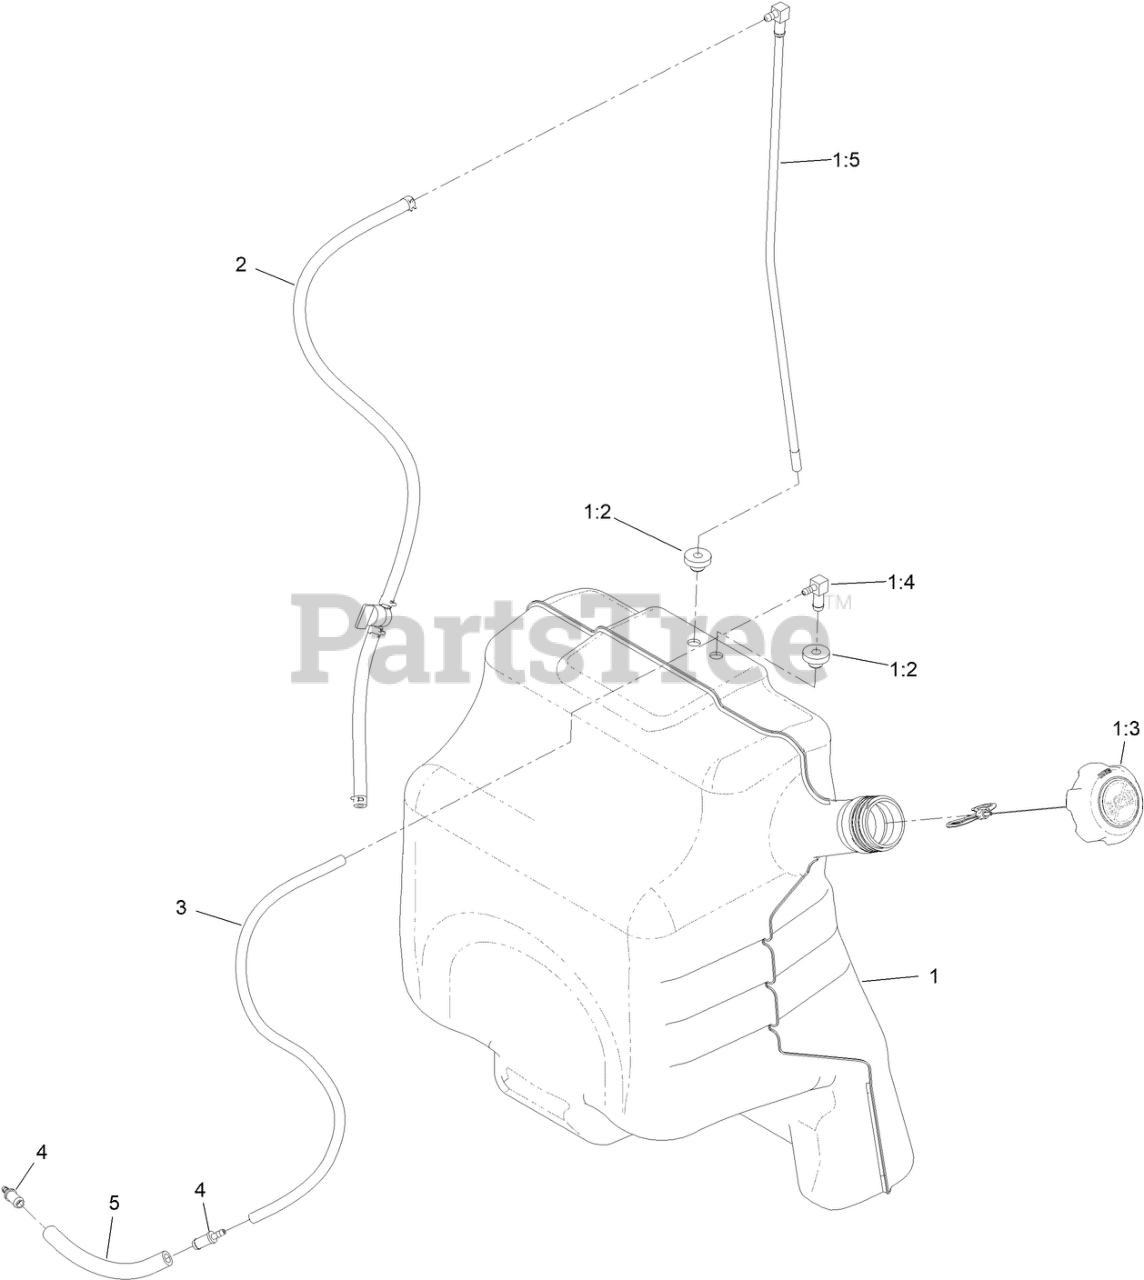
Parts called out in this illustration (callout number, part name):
1	FUEL TANK ASM
1:2	BUSHING
1:3	CAP-FUEL
1:4	FITTING-ELBOW, 90 DEG
1:5	ASM, TUBE-FUEL
2	FUEL LINE ASM
3	HOSE-FUEL
4	FITTING-STRAIGHT
5	HOSE-FUEL
